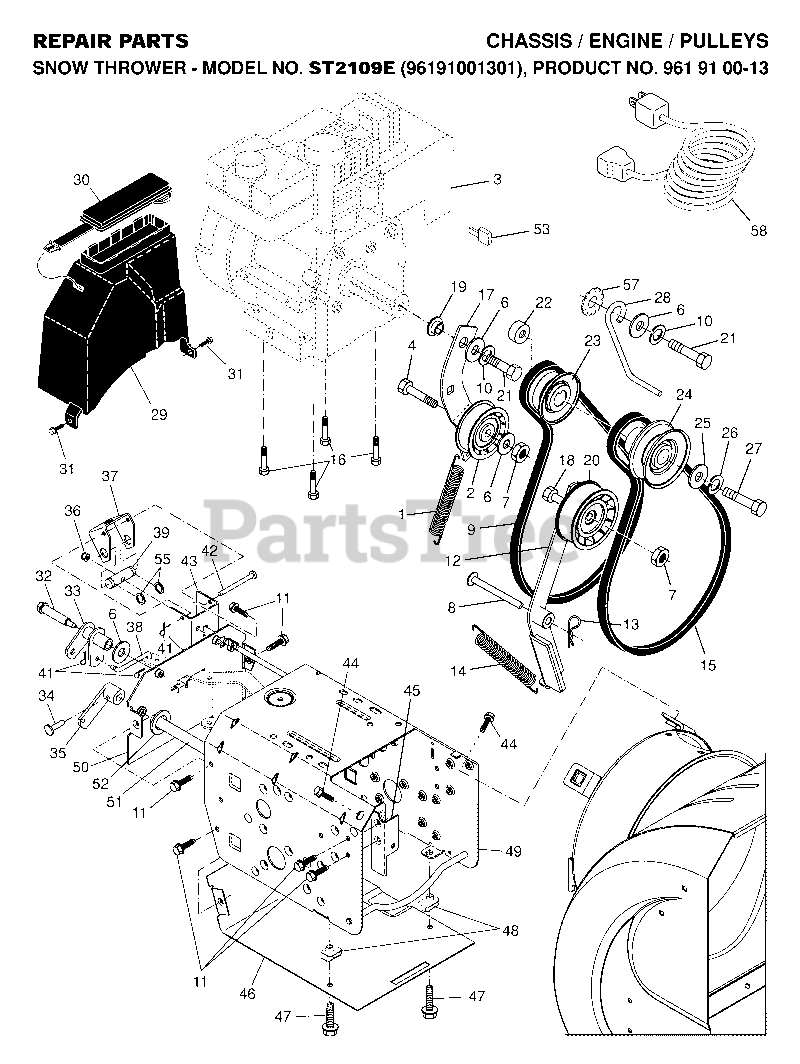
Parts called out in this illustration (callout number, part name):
1	RP SPRING, TRACTION IDLER
2	PULLEY.W/SPACER.2.25
4	BOLT.5/16-18X1-1/4 FULL.THREAD
6	STEEL WASHER
7	LOCKNUT 5/16-18
8	PIN, IDLER PIVOT
9	V-BELT, TRACTION DRIVE
10	WASHER, LOCK 5/16
11	SCREW, HEX HEAD 5/16-18 X 1/2
12	ARM ASSEMBLY, IMPELLER IDLER
13	RETAINER CLIP PM
14	SPRING, BRAKE
15	V-BELT, IMPELLER DRIVE
16	BOLT 3/8-16X1-1/8
17	IDLER ARM
18	HEX BOLT
19	BUSHING, IDLER PIVOT
20	PULLEY.W/SPACER.2.75
22	SPACER, ENGINE PULLEY
23	PULLEY, ENGINE TRACTION DRIVE
24	PULLEY
25	WASHER, FLAT 3/8
26	LOCKWASHER
27	SCREW, HEX HD 3/8-24 X 1-3/8
28	GUIDE BELT
29	COVER.ASM.BELT/STORAGE
30	COVER.STORAGE.SNOW
31	SCREW, HEX HEAD 1/4-20
32	BOLT, SHOULDER 5/16-18
33	BELLCRANK SHIFTER
34	CLEVIS PIN
35	ARM, AUGER CONTROL
36	NUT.71038.31-18.HEX.NYLOCK
37	BRACKET, PIVOT
38	LINK, SPEED CONTROL
39	TRUNNION, TRACTION
41	RETAINER CLIP
42	PIN, PIVOT BRACKET
44	SCREW 3/8-16X1
45	BRACKET, IDLER PIVOT
46	PAN, FRAME BOTTOM
47	SCREW, HEX HD 5/16 -18 X 3/4
48	NUT, SPEED 5/16-18
51	SHAFT, AUGER CONTROL
52	THRUST WASHER
53	KEY, SAFETY IGNITION (BRIGGS)
55	RETAINING RING LT
57	WASHER EXT TOOTH LOCK 5/16
